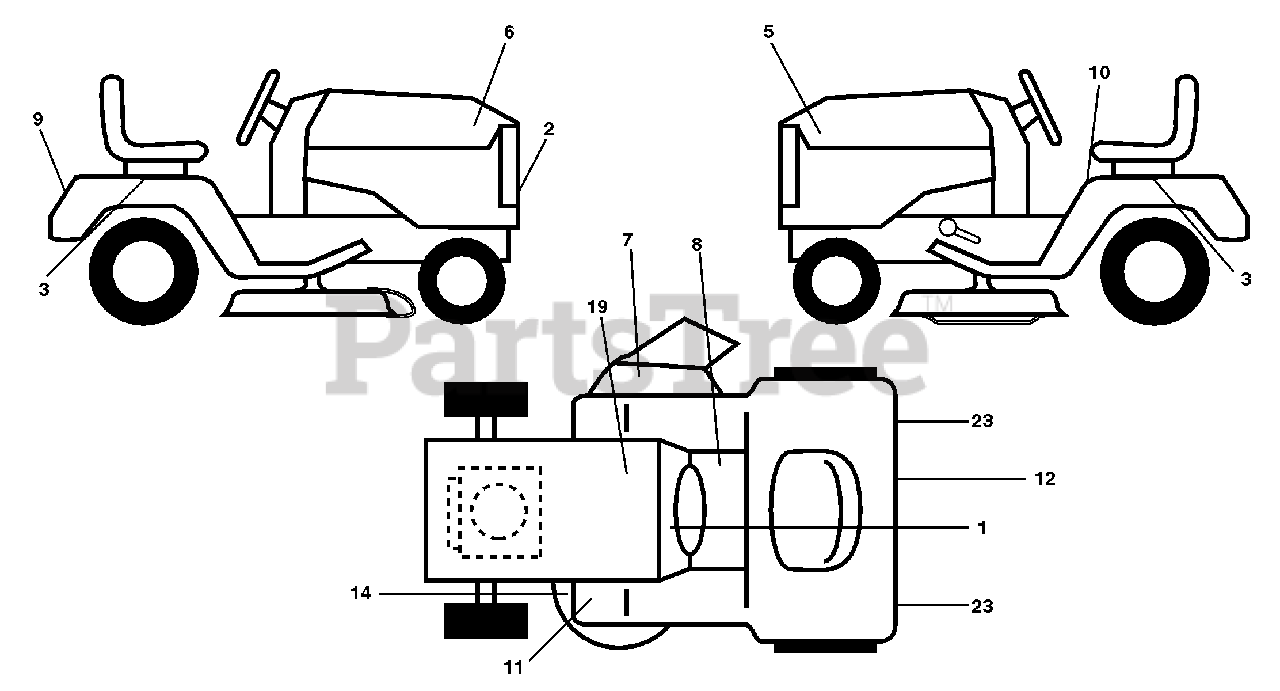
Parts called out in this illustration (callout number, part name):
1	Decal, Operating Instruction
2	Decal, Grille Husqvarna
3	Decal, Fender Automatic
5	Decal, Inst Hood LH GTH220 Hydro
6	Decal, Insrt Hood RH GTH220 Hydro
7	Decal, Warning Multi-Language
8	Decal, Brake Parking Saddle
9	Decal, Fender
10	Decal, Danger
11	Decal, Clutch/Brake
12	Decal, D-Bar Ctrl. Mvt Hyd YT/GT
14	Decal, V-Belt Schematic
19	Decal, Battery
23	Reflector, Taillight
